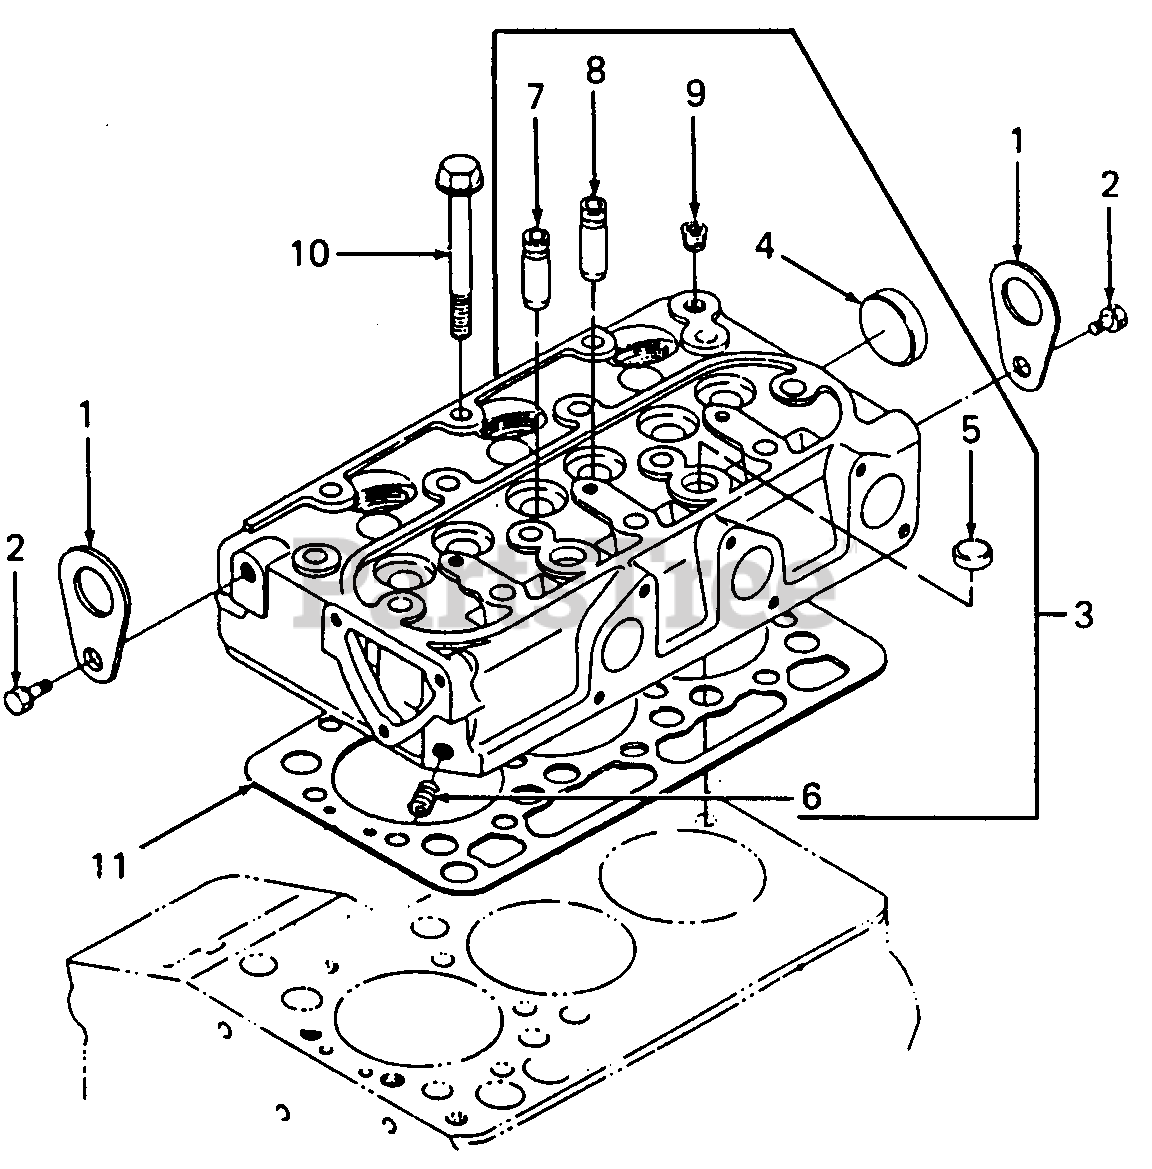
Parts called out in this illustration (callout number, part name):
3	Cylinder Head Assy
7	Guide, Intake Valve
8	Guide, Exhaust Valve
10	Bolt, Cylinder Head
11	Gasket, Cylinder Head
